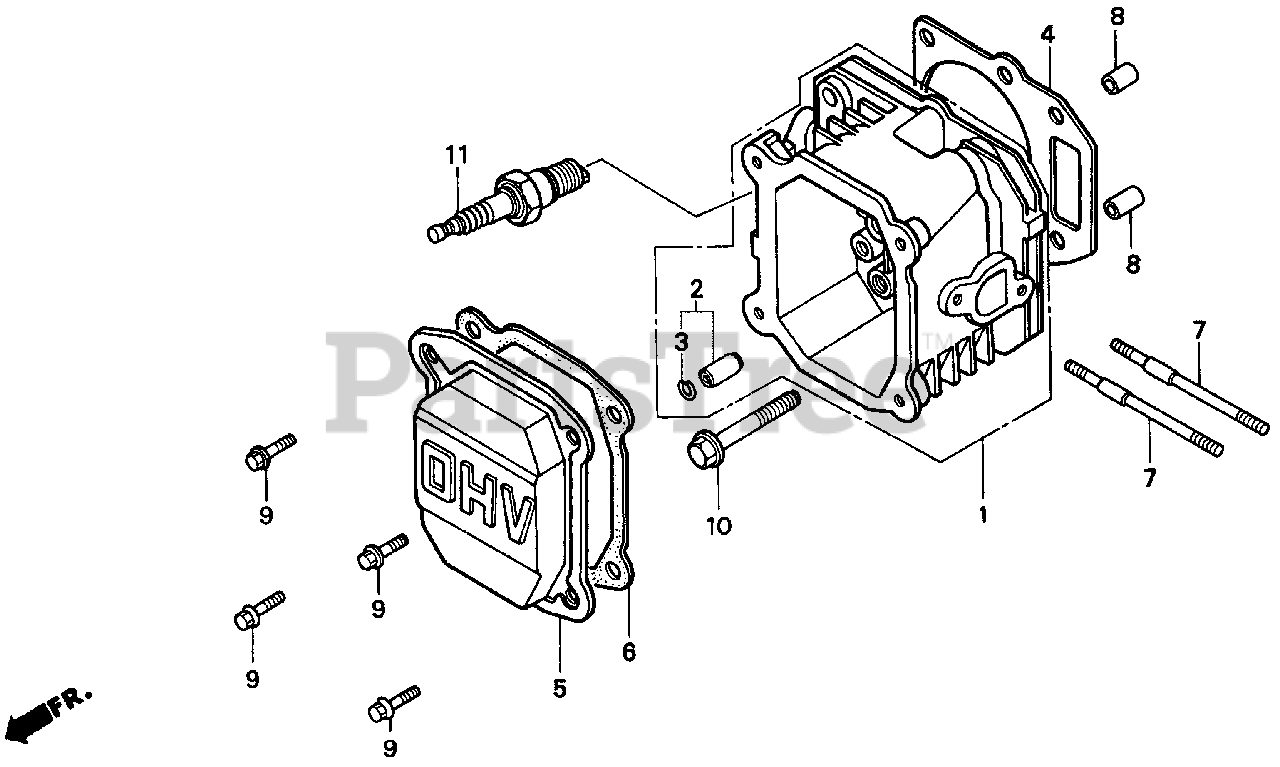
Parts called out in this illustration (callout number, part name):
1	CYLINDER HEAD (USA)
2	GUIDE, EX. VALVE (OS)
3	CLIP, VALVE GUIDE Use from Engine SN 1231803.
4	GASKET, CYLINDER HEAD
5	COVER, HEAD
6	GASKET, HEAD COVER
7	BOLT, STUD (6X83)
8	PIN A, DOWEL (10X16)
9	BOLT, FLANGE (6X14)
10	BOLT, FLANGE (8X50)
11	SPARK PLUG (BPR4ES) (NGK)
11	SPARK PLUG (BPR5ES) (NGK)
11	SPARK PLUG (BPR6ES) (NGK)
